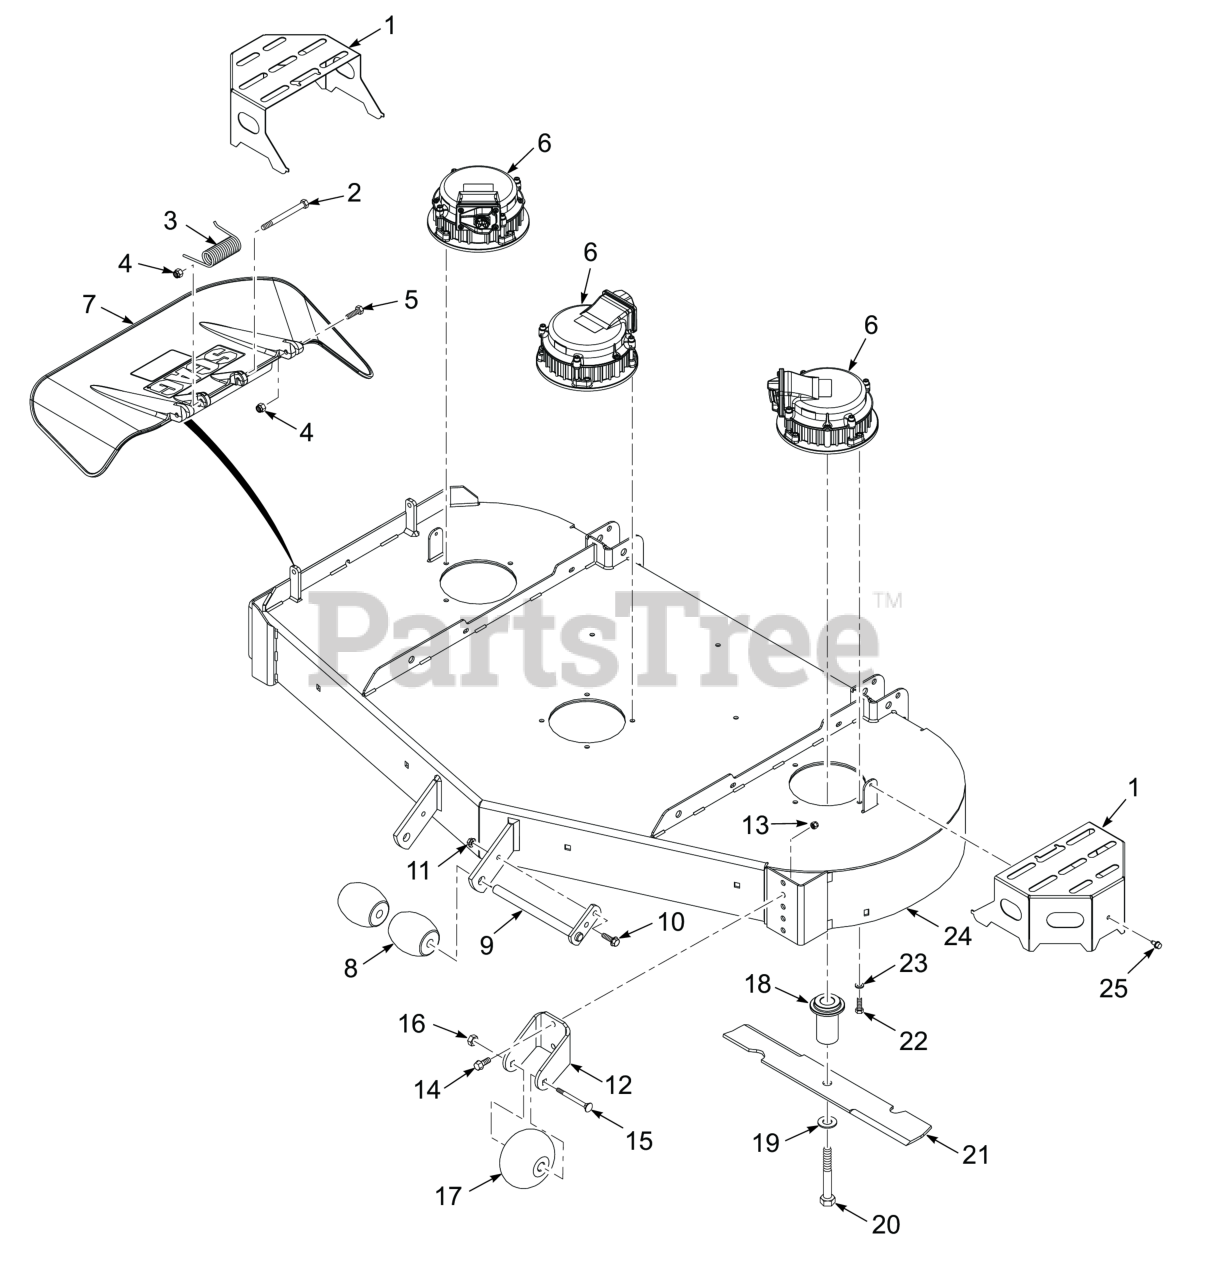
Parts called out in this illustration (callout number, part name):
1	Cover, Deck Motor
2	Bolt, 5/16-18 x 4-3/4" Hex Head
3	Spring, Discharge Chute
4	HEX NUT, ELASTIC STOP LOCK, 5/16-18
5	Bolt, Hex Head 5/16-18 x 1-1/2" - Front
6	Deck Motor
7	Discharge Chute Assy. SFZ52
8	Wheel, Anti-Scalp
9	Shaft Weldment, Guide Roller
10	Bolt, Heax Head 5/16-18 x 1" (48V / 52V)
11	Nut, Flange Head Elastic Stop 5/16-18
12	Bracket, Anti-Scalp, (Black)
13	HEX NUT, ELASTIC STOP LOCK, 3/8-16
14	Capscrew, 3/8-16 x 1.0" Serrated Flange Hex Hd
15	Bolt, Hex Head 3/8-16 x 3-1/2"
16	Bolt, Hex Head 3/8-16 x 1" Ser. Flg.
17	Bolt, Carriage 3/8-16 x 4"
18	Blade Driver
19	Washer, Flat, 1/2-.562 x 1.375 x .109 HD
20	Bolt, Hex Head 1/2-13 x 4" (lower)
21	Cutter Blade, EVZ 18"
22	Bolt, 5/16 - 18 x 1 - 1/4" Hex Head
23	Lockwasher, 5/16 (.317 x .586 x .078) Helical Spring
24	Cutter Deck w/Decals
25	Screw, 1/4-20 x .375"
